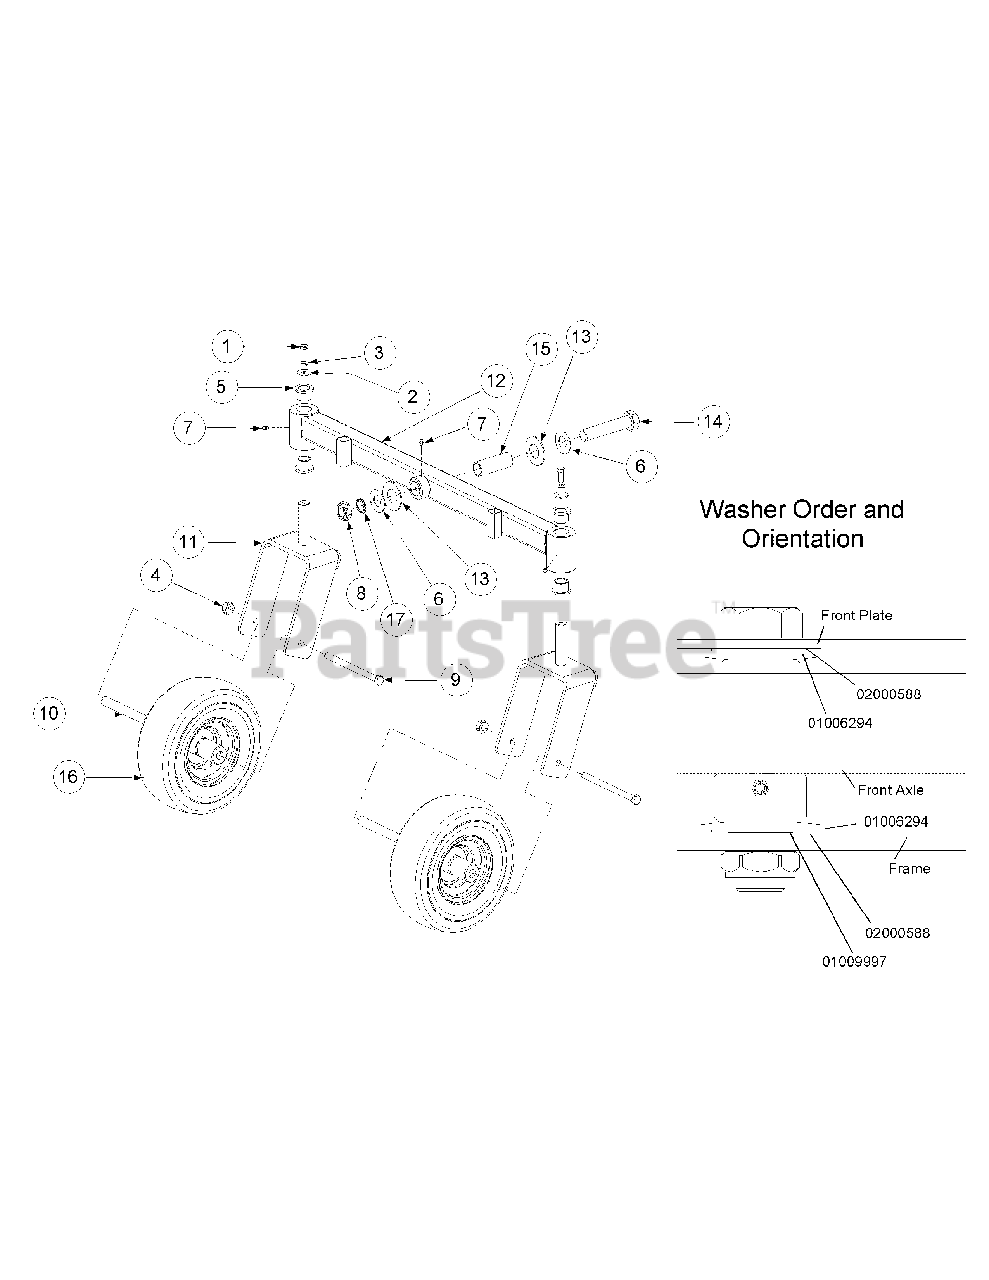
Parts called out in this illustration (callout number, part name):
1	Hex Cap Screw, 3/8-16, x 1
2	Flat Washer, .411 x 1.25 x 1.00
3	Lock Washer, 3/8
4	Center Lock Nut, 1/2-20
5	Flange Bearing, 1.013
6	Flat Washer, 1.00 ID x 2.00 OD x .075
7	Grease Fitting, 1/4-28 x 3/16
8	Jam Lock Nut, 1.0-14
9	Hex Cap Screw, 1/2-20 x 7.25
10	Spacer, .51 ID x .75 OD x 5.925 Lg
11	Caster Wheel Bracket Assembly
12	Narrow Front Axle Assembly
13	Belle Washer, 1.25 ID x 2.500 OD x .1
14	Hex Cap Screw, 1-14 x 5.0
15	Spacer, 1.005 ID x 1.25 OD x 3.6
16	Wheel Assembly, 11 x 4-5.00 includes:
17	Retainer Extension, Self Locking
